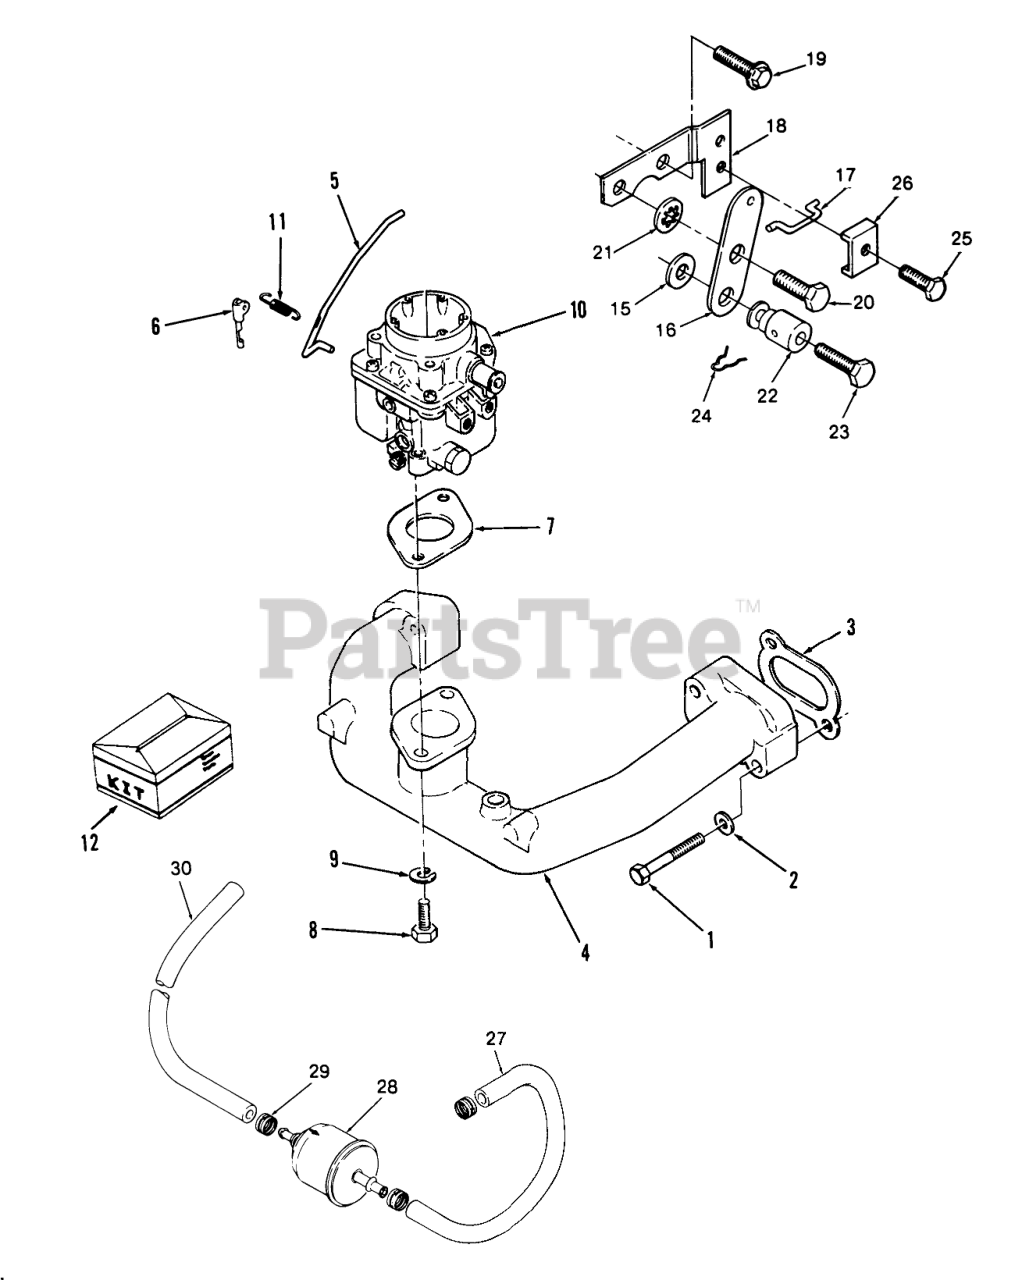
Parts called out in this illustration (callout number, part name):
2	Nut-M8
3	Gasket
4	Manifold
6	CONTROL-ROD CLIP
7	Gasket
8	HEX-HEAD CAP SCREW
9	Washer
10	COMPLETE-CARBURETOR
11	SPRING
12	Kit-Repair
15	Washer
16	SWIVEL-CHOKE
17	LINK-CHOKE
18	BRACKET
19	Bolt
20	BOLT-SHOULDER
21	Lockwasher
22	SWIVEL
23	Bolt
24	PIN-COTTER
25	Bolt
27	Hose
28	Filter-Fuel
29	Clamp
30	Hose
